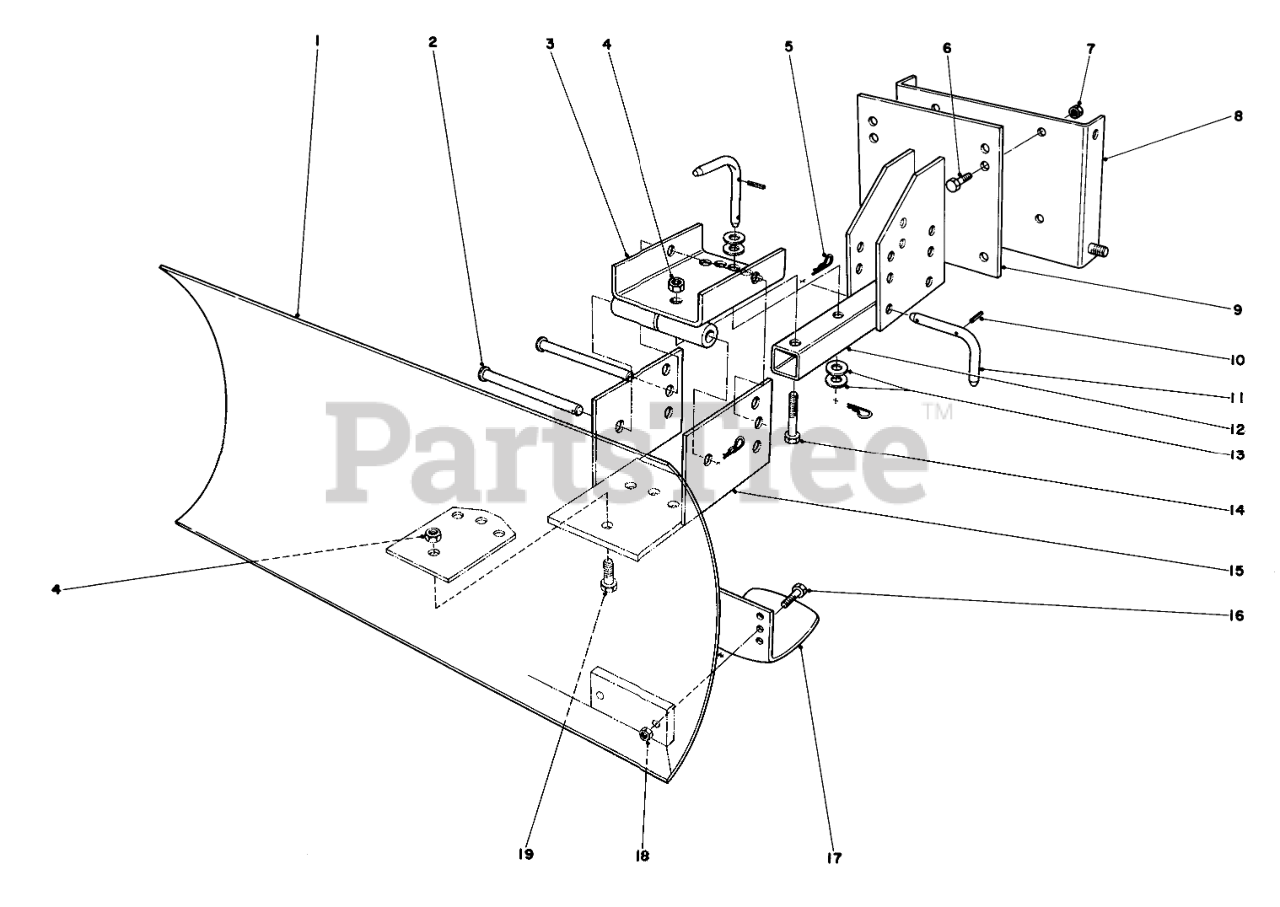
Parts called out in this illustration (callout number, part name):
1	Blade
2	PIN-CLEVIS
3	Swivel Bracket
4	1/2-13 CONELOCK NUT
5	PIN-HAIR
6	SCREW-HH
7	NUT-LOCK, CONE
8	Mounting Plate (Used with 826 & 1132 Units only)
9	Mounting Plate
10	PIN-SPRING
11	Pivot Pin (Incl. Ref. #10)
12	Blade Tongue
13	WASHER-FLAT
14	SCREW-HH
15	Blade Adjustment
16	SCREW-HH
18	NUT-LOCK, CONE
19	SCREW-HH
